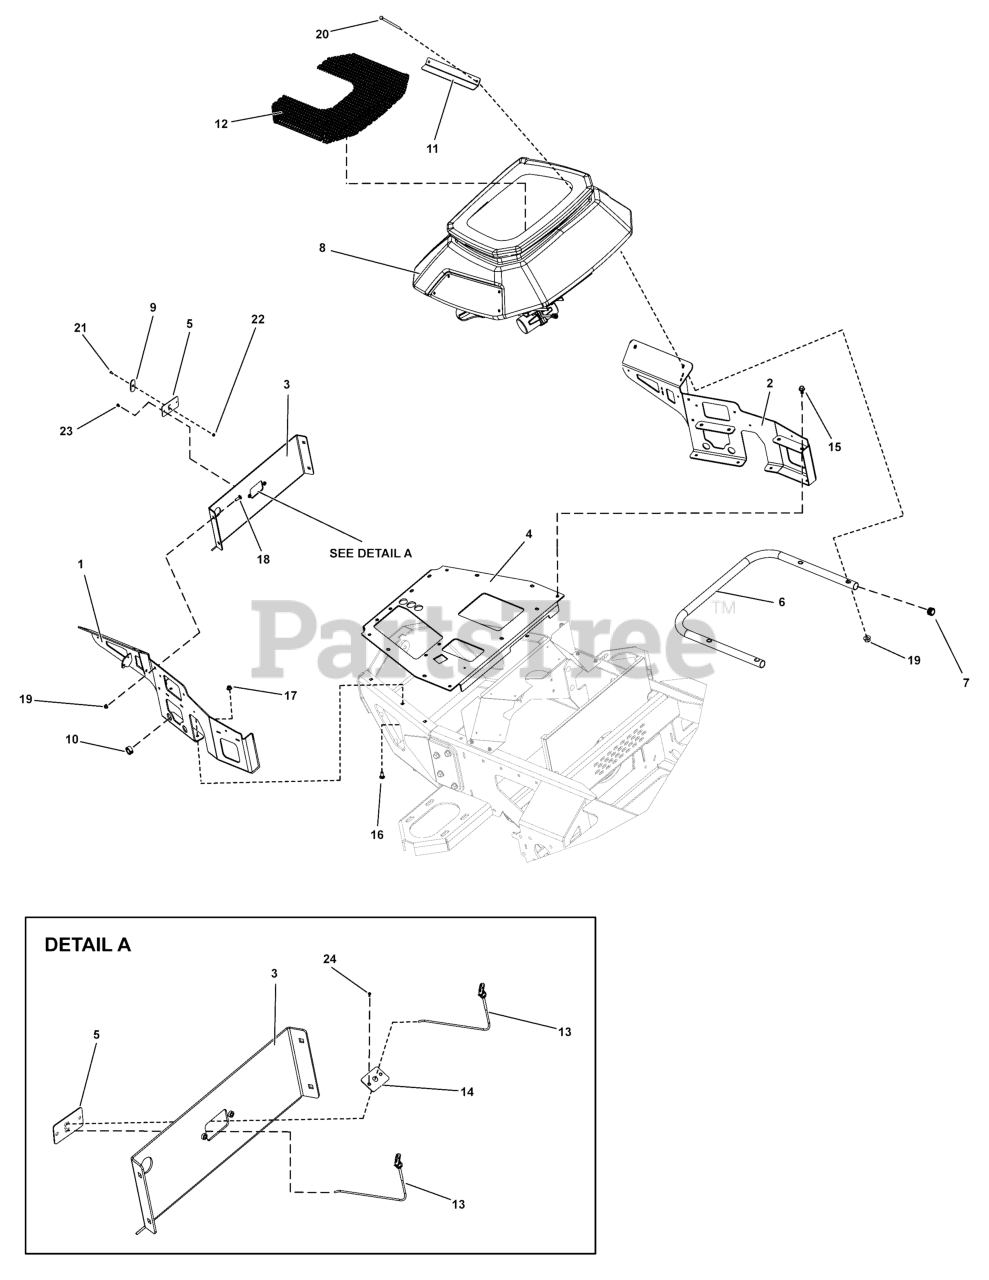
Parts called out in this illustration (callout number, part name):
1	WELD, LH HOPPER SUPPORT
2	WELD, RH HOPPER SUPPORT
3	BRACE, FRONT
4	PLATE, FORWARD COMPONENT ORG
5	PLATE, HOPPER CABLES
6	TUBE, MOUNT LIGHT BAR - PAINTED
7	PLUG TUBE INSERT 1.25" O.D.
8	Refer to: Hopper Group
9	PLATE, CABLE HOLDER
10	BUSHING, SNAP 1" ID
11	BRACKET, SCREEN SUPPORT HOPPER
12	SCREEN, HOPPER FS5250
13	CABLE, TURN-TO-LOCK 35" LONG
14	PLATE, HOPPER CONTROL VOYAGER
15	SCR-CAP, HSWH .375"-16 X .750" SS188
16	BLT-RDHDSQNK, .375"-16 X 1.000" SS188
17	NUT-HEX-NYLK, FLG .375"-16 SS188
18	BLT-RDHDSQNK, .3125"-18 X 1.000" SS188
19	NUT-HEX-NYLK, FLG .3125"-18 SS188
20	SCR-CAP, HEX .3125"-18 X 2.250" SS188
20	BLT-RDHDSQNK, .3125"-18 X 2.250" SS188
21	SCR-CAP, BSH #10-24 X .500" SS188
22	NUT-HEX-NYLK, #10-24 SS188
23	SCR-CAP, SBH .250"-20 X .375" SS188
24	SCR-CAP, SBH .250-20 X .750" SS188
